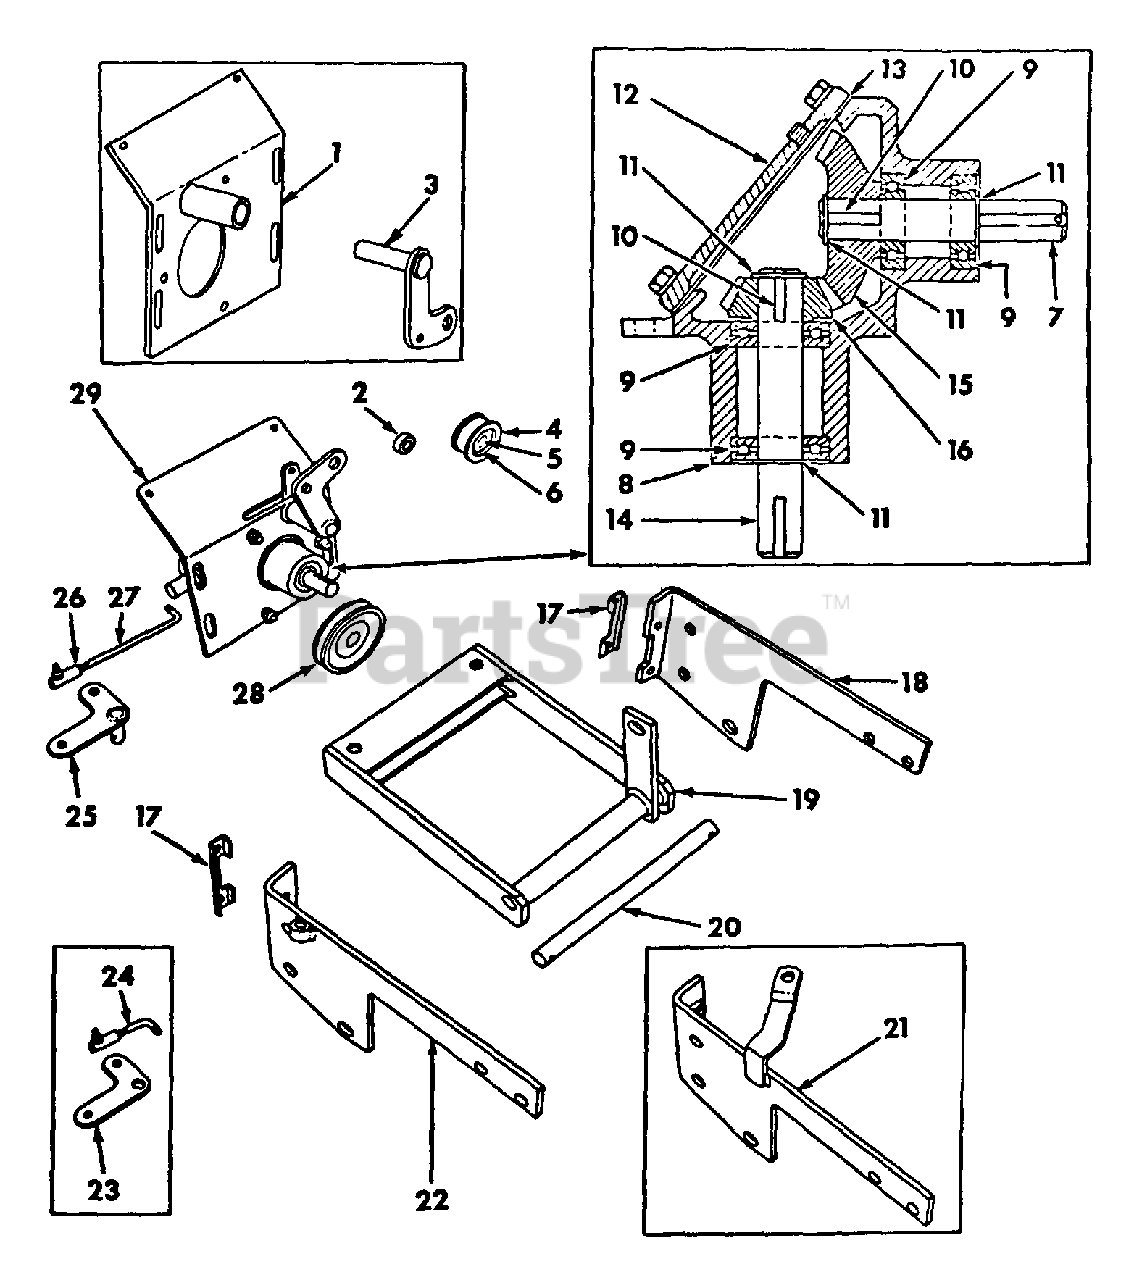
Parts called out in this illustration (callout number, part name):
1	PLATE ASSY, FRONT
2	SPACER
3	ARM, IDLER
4	IDLER
5	BEARING ASSY, IDLER
6	RING, IDLER SNAP
7	SHAFT, OUTPUT
8	BOX GEAR
9	BEARING, BALL
10	KEY, 3/16 X 11/16 SQ PARALLEL
11	RING, RETAINING SNAP
12	COVER GEAR BOX
13	GASKET, GEAR BOX COVER
14	SHAFT, INPUT
16	GEAR, BEVEL PINION
17	CLIP, LOCKING
18	PLATE RH SIDE
19	BRACKET ASSY, LIFT
20	SHAFT PIVOT
21	PLATE ASSY, LH SIDE
22	PLATE ASSY LH SIDE
23	BELLCRANK
24	LINK
25	BELLCRANK
26	JOINT, 1/4 BALL
27	LINK
28	PULLEY, GEAR BOX
29	PLATE ASSY, FRONT
17452-R1	BOLT, 1/2 X 1-1/4 C-Z HEX-HD MACH
17452-R1	BOLT 1/2-13 X 1-1/4 HEX-HD MACH
18475-R1	BOLT, 5/16-18 X 1-1/4 C-Z HEX-HD MACH
124589	NUT, 5/8-11 C-Z HEX.
180020	SCREW, 1/4-20 X 3/4 C-Z HEX-HD CAP
180175	SCREW, 1/2-13 X 1-1/4 C-Z HEX-HD CAP
